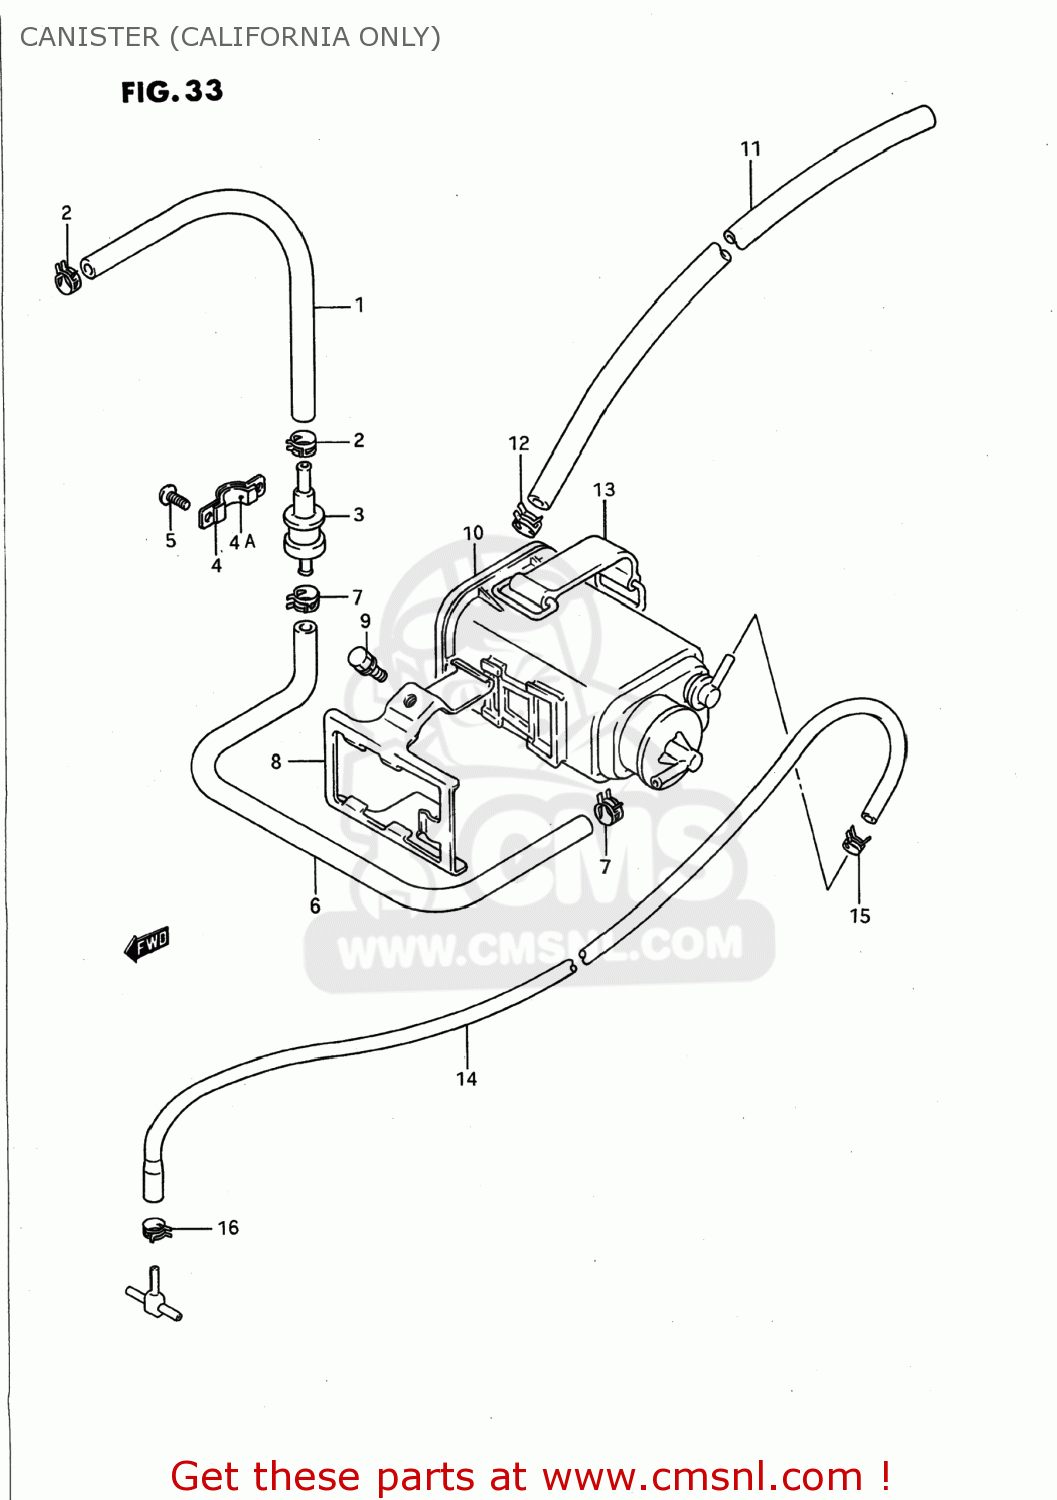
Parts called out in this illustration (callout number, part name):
1	HOSE (5.4X11.4X600)
2	CLIP
3	VALVE,FUEL TANK BREATHER
4	PLATE,FUEL TANK BREATHER NO.2
4A	CUSHION
5	SCREW
6	HOSE(5.4X11.4X350)
7	CLIP
8	PLATE,CSTR FITING
9	BOLT
10	CANISTER ASSY,CHARCOAL
11	HOSE (7X12X600)
12	CLIP
13	BAND
14	HOSE(3.5X7.5X600)
15	CLIP
16	CLIP
